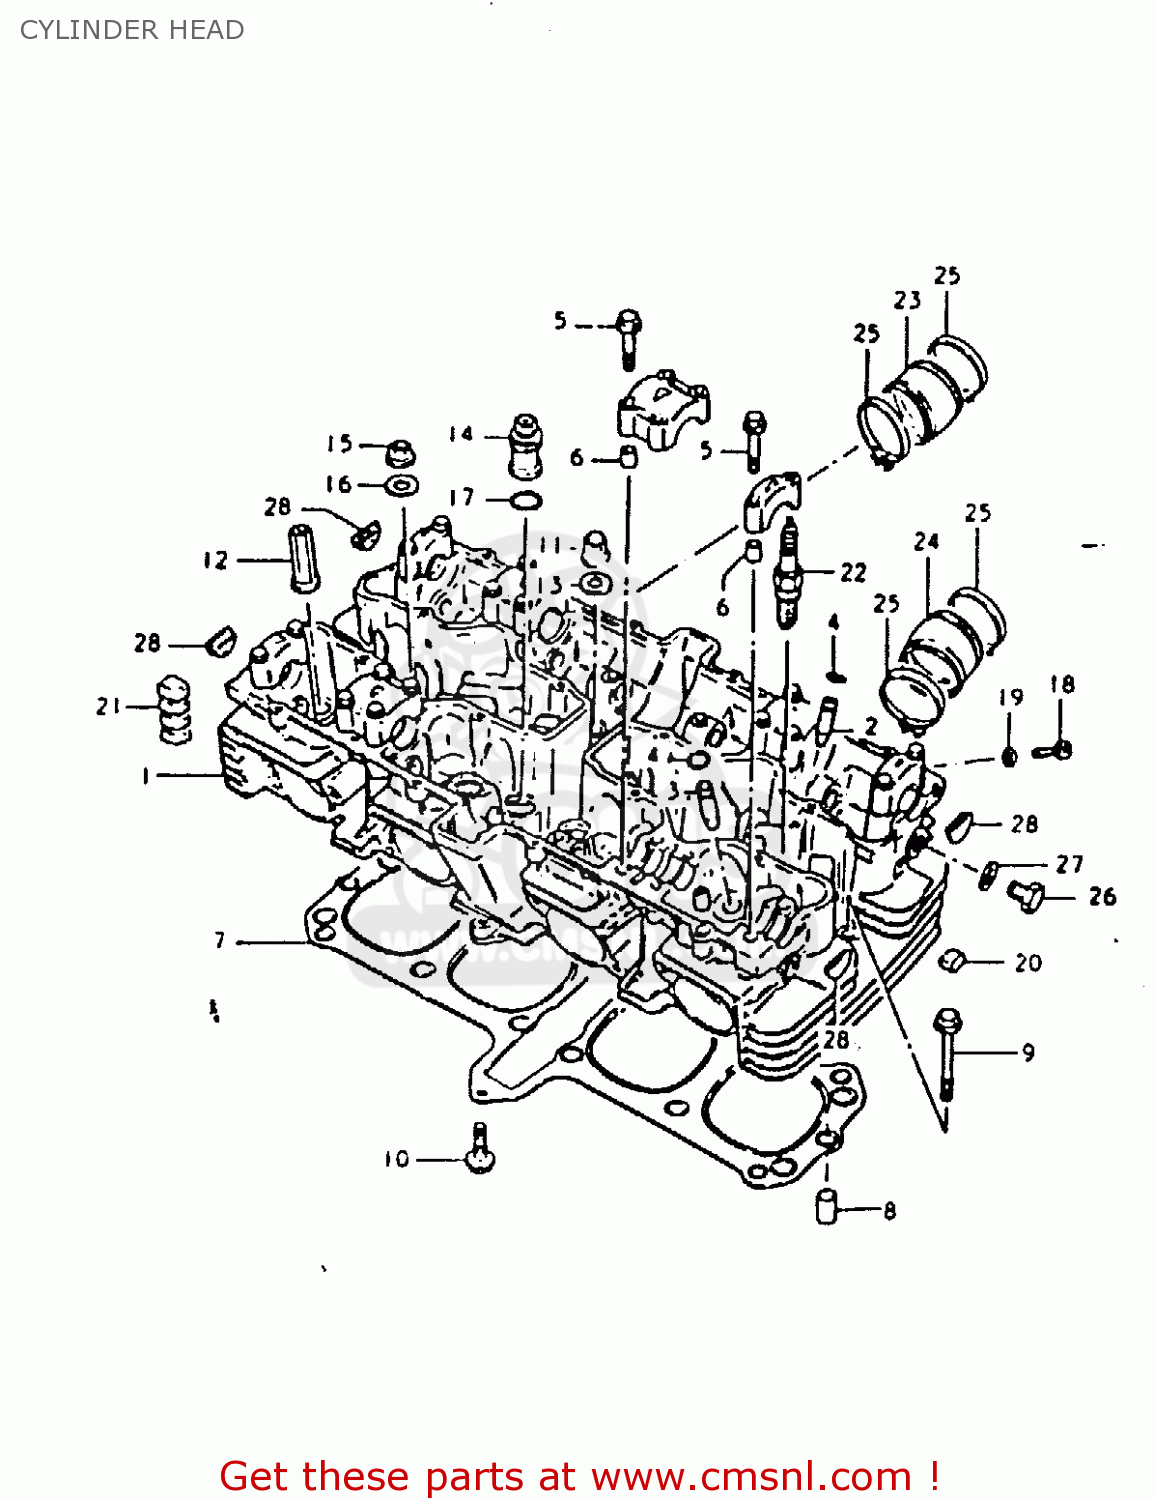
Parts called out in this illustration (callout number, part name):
1	HEAD ASSEMBLY,CYLINDER
2	GUIDE,INTAKE VALVE
3	GUIDE,INTAKE VALVE
4	RING,SNAP
5	BOLT(6X39)
6	PIN(6.2X8X11)
7	GASKET,CYLINDER HEAD (NAS)
8	PIN
9	BOLT
10	BOLT
11	NUT
12	NUT
13	GASKET (NAS)
14	NUT,CYLINDER HEAD SEAL
15	NUT
16	WASHER(10.5X22X2.3)
17	O RING(D:2.4,ID:16.8)
18	BOLT
19	GASKET(5.3X9.3X1.2) (NAS)
20	PAD
21	PAD,CYLINDER
22	SPARK PLUG DR8ES-L
23	PIPE,INTAKE,R
24	PIPE,INTAKE,L
25	CLAMP
26	PLUG (14X12)
27	GASKET(14X19.2X2) (NAS)
28	PLUG
